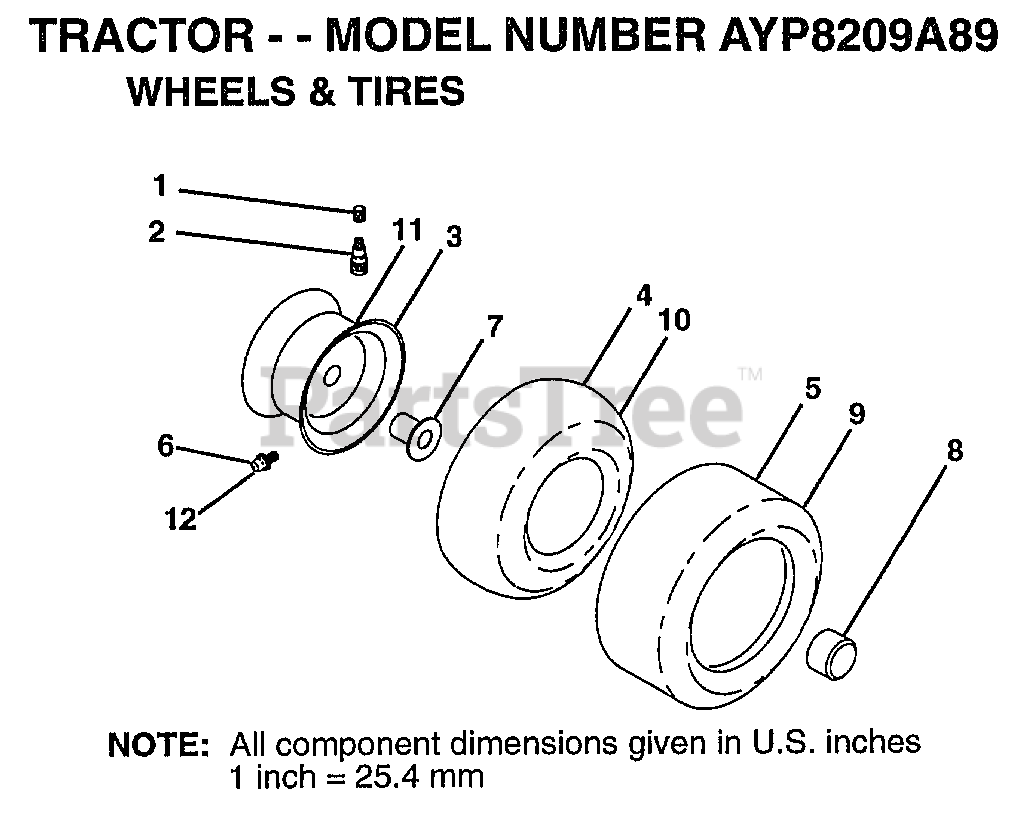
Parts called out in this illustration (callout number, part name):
1	VALVE CAP
2	VALVE STEM LT
3	"RIM ASM 8"" FRT"
4	TUBE.16X6.5/7.5-8
6	FITTING LT
7	"FLANGE, BEARING"
8	HUB CAP
10	TUBE.23X8/10-12
11	"RIM ASM 12"" REAR"
12	ZERK FITTING M
